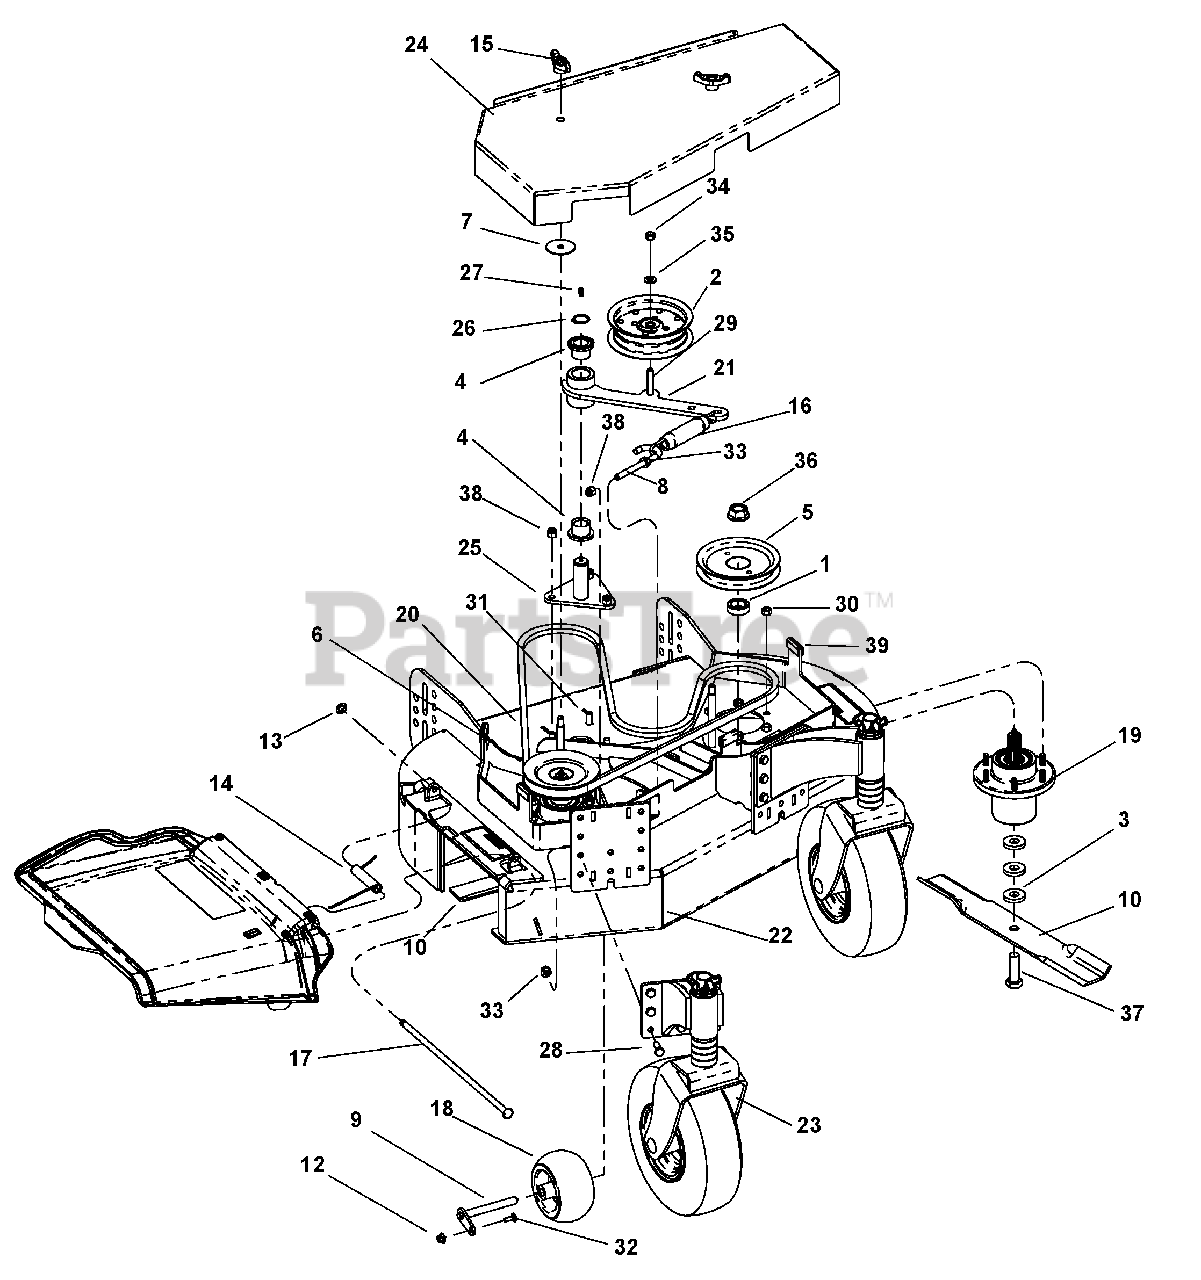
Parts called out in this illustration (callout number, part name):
1	Spacer, 1.500 x 1.000 x .510 Y
2	Pulley, Flat 5.0 x .38 w/Bearing
3	Washer, Blade
4	Bearing, Flg 1.00 x 1.25 x 1.00
5	Pulley, Spline Spindle Offset
6	Pulley, V-belt 5.27 x .990 w/Spl
7	Washer, .402 x 2.00 x .055 Fend Y
8	J-bolt, 3/8-16 x 4.00 Y
9	Pivot, Retainer Weld
10	Blade, 16.50 Lo-Lift
11	Blade, 18"
12	Nut, 1/4" Flange Prevailing Tor
13	Retainer #
14	Spring,chute Guard
15	Knob, Locking
16	Spring, Tension
17	Discharge Chute, 48" Deck
18	Wheel, Gage
19	Assy, Spindle Housing
20	Belt, HB 80.3 El AMD OHR
21	Weldment, Idler Arm
22	Weldment, 34" Deck
23	Assy, Fr Wheel Caster
24	Shield, Deck 34
25	Weldment, Idler Pivot
26	Snap Ring, 1.00 x .042 Ext
27	Grease Zerk, 1/4-28 Straight .69 LG
28	Bolt, Hex Round Head Square Neck .38-16 x 1.00 Grade 5
29	Bolt, 3/8-16 x 2.25 Hex 5 Y
30	Nut, Hex .31-18
31	Bolt, .38-16X1 Grade 5
32	Bolt, 1/4-20 x .750 Crg 5 Y
33	Nut, Flange .375-16
34	Nut, .38-16 Low Crown Locking Acorn
35	Washer, .406 x .813 x .065 Flat Y
36	Nut, 3/4-16 Flange Gr8 Y
37	Bolt, 5/8-11 x 2.00 Hex 8 Y
38	Nut, Locking-Nylon .38-16
39	Trim 1/4
